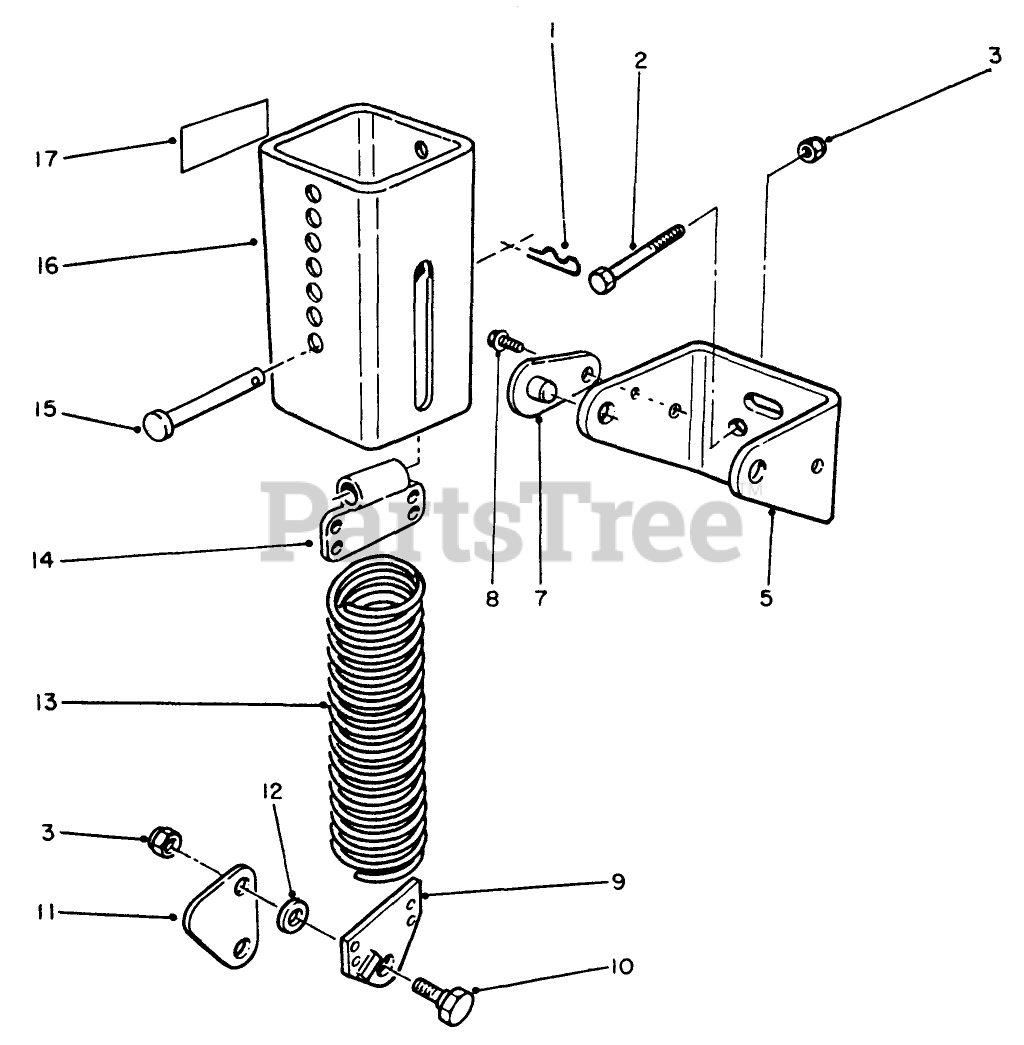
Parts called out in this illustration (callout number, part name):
1	PIN-HAIR
3	NUT-LOCK, NI
5	Bracket-Mounting
7	PIN-LOCK
8	SCREW
9	End Spring
10	BOLT-SHOULDER
11	Link Knee
12	WASHER-FLAT
13	Spring-Extension
14	End Spring
15	PIN-CLEVIS
16	Asm-Spring Cover
17	DECAL-WARNING
